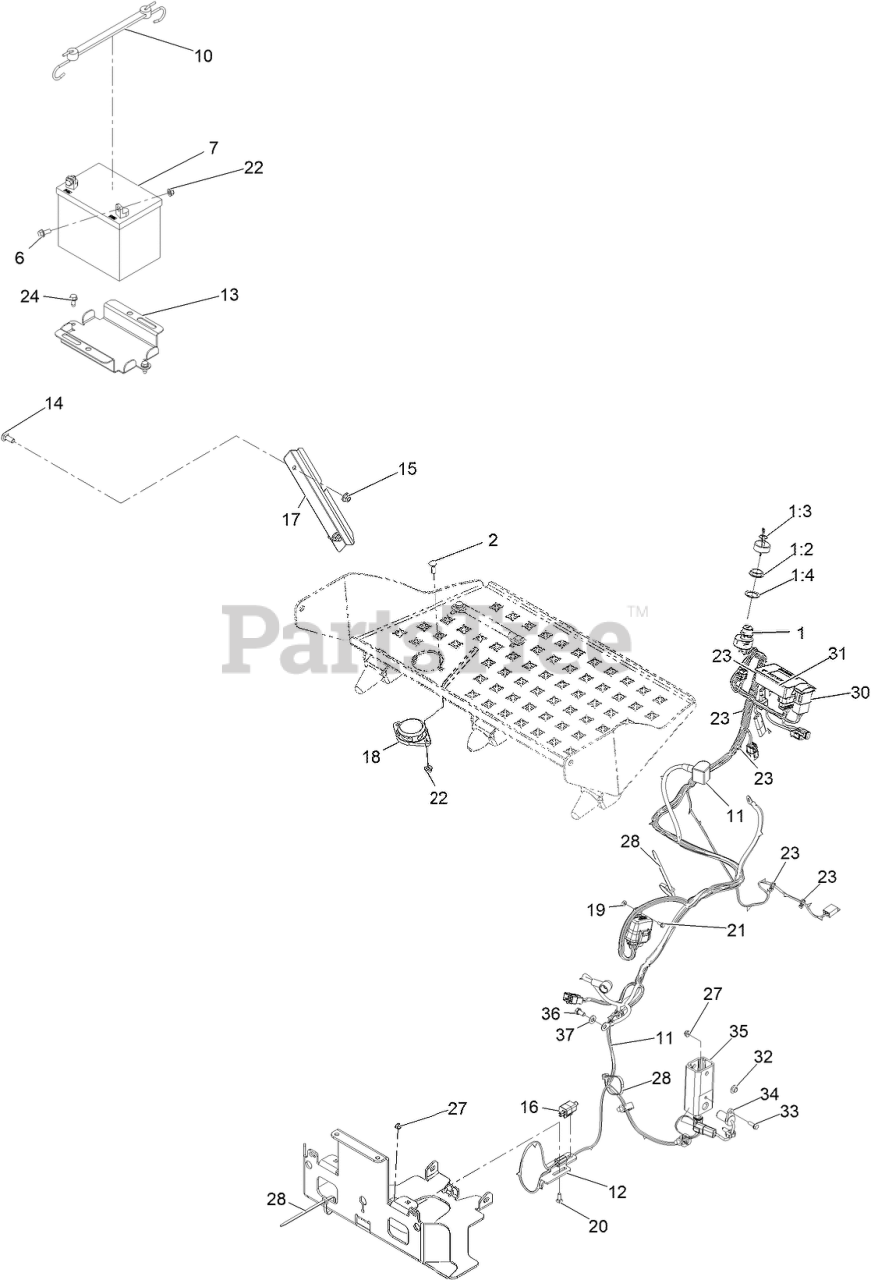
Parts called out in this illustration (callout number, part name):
1	IGNITION SWITCH ASM
1:2	NUT-MOUNTING
1:3	IGNITION KEY SET
1:4	WASHER-BACKUP
2	BOLT-CARR
6	SCREW-HHF
7	Battery
10	HOLDDOWN-BATTERY
11	Harness-Wire
12	MOUNT-SWITCH
13	BRACKET-BATTERY
14	BOLT-CARR
15	NUT-HF, NI
17	GUARD-HARNESS
18	SWITCH-SEAT
19	NUT-LOCK, NI
20	BOLT-CARR
21	SCREW-HWH
22	NUT-HF, NI
23	TIE-CABLE
24	Screw-HWH 5/16-18 X 3/4 Tf
28	TIE-CABLE
31	Hour Meter ASM
32	Nut-Push
33	SCREW-HWH
34	Sensor, Quadrature
35	Housing-Depth Control 30
36	SCREW-HH
37	WASHER-PLAIN
